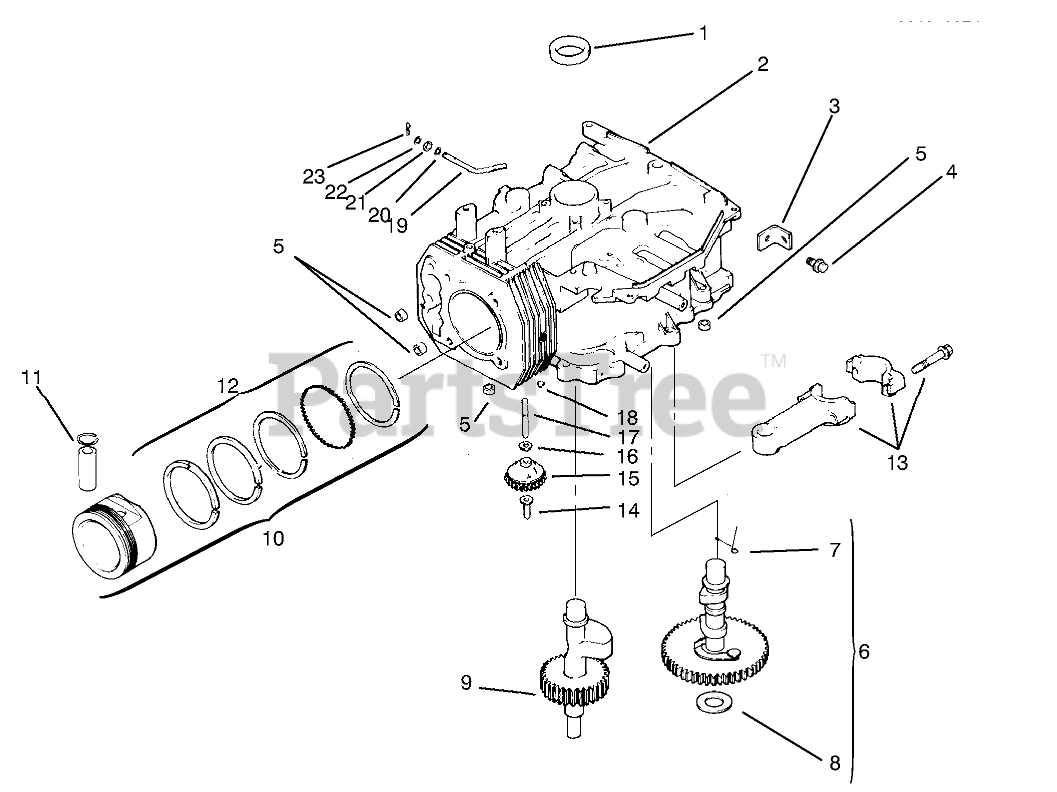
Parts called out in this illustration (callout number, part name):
1	Seal-Crankshaft
2	Block-Short
3	Strap-Lifting
4	Screw
5	Pin-Dowel
6	Camshaft Assembly
7	Spring-Actuating
8	Shim-Camshaft
9	Shaft-Balance
10	Piston ASM STD Incl 11-2
10	Piston ASM .25 Incl 11-2
10	Piston ASM .50 Incl 11-2
11	Retainer-Piston Pin
12	Ring Set STD
12	Ring Set .25
12	Ring Set .50
13	Rod Connecting STD
13	Rod Connecting .25
14	Pin-Governor
15	Gear, governor
16	Washer
17	Shaft-Gear, Governor
18	Plug
19	Kit-Governor Cross
20	Washer, plain 6 mm
21	Seal-Cross Shaft
22	Washer
23	Clip-Hitch Pin
